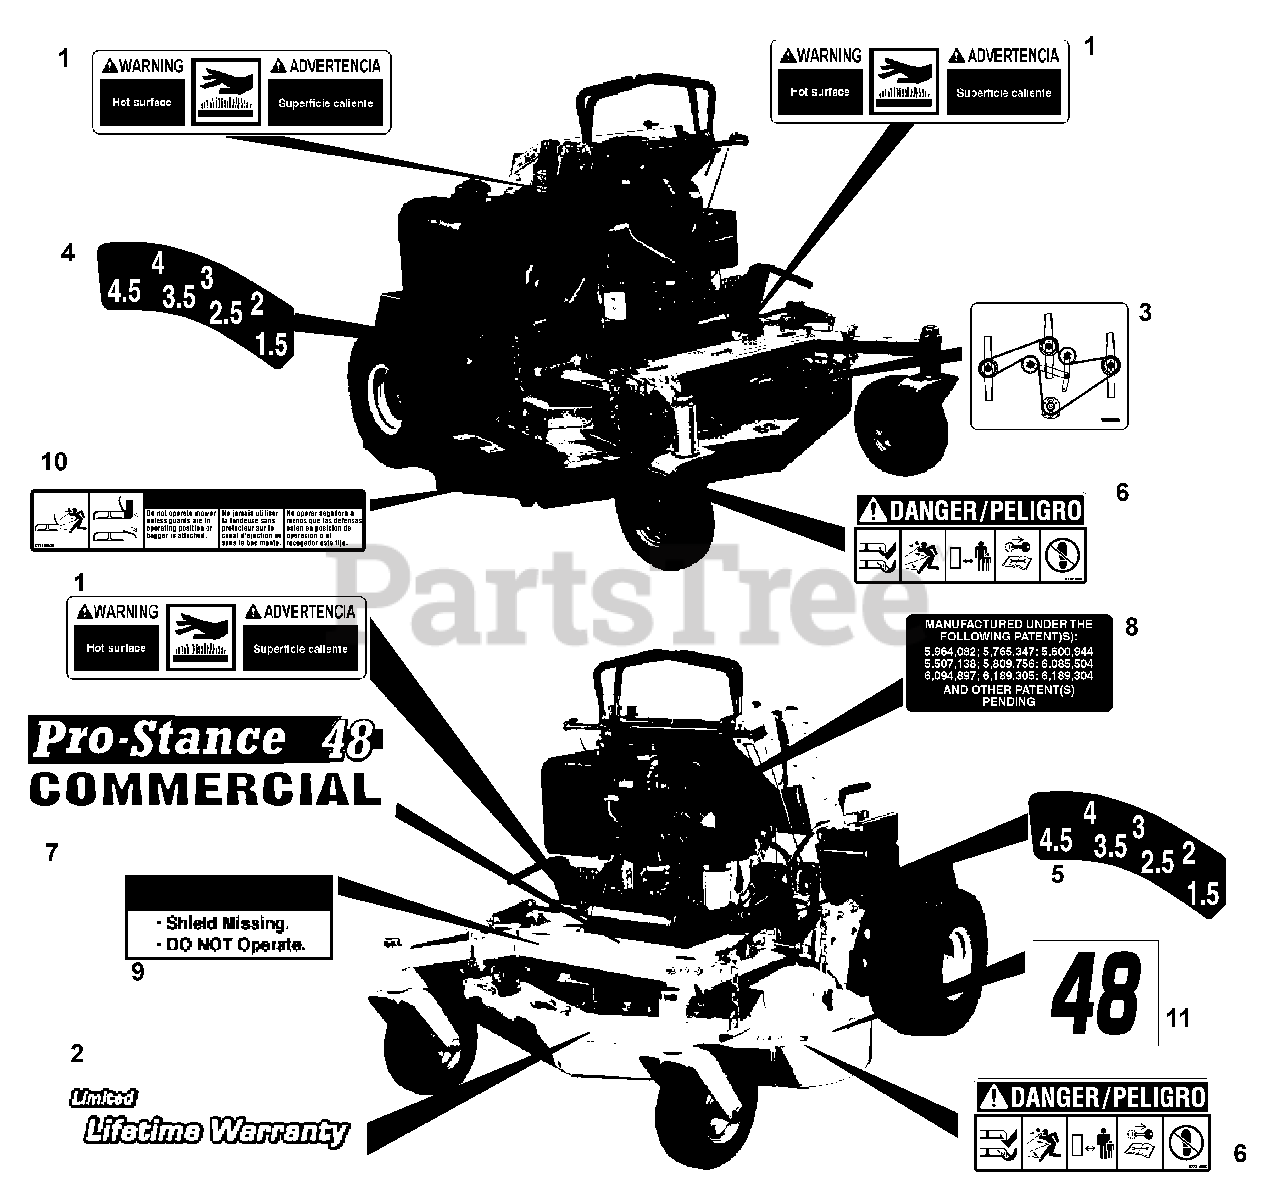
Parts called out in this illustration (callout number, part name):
1	Decal, Warning, Label (Eng/Sp)
2	Decal, Limited Lifetime Warranty
3	Decal, Belt Path
4	Decal, Cut Height RH
5	Decal, Cut Height, LH
6	Decal, Mower Fan Danger
7	Decal, Pro-Stance 48" (994109)
8	Decal, Patent
9	Decal, Warning, Shield
10	Decal, Warning, Discharge
11	Decal, 48"
